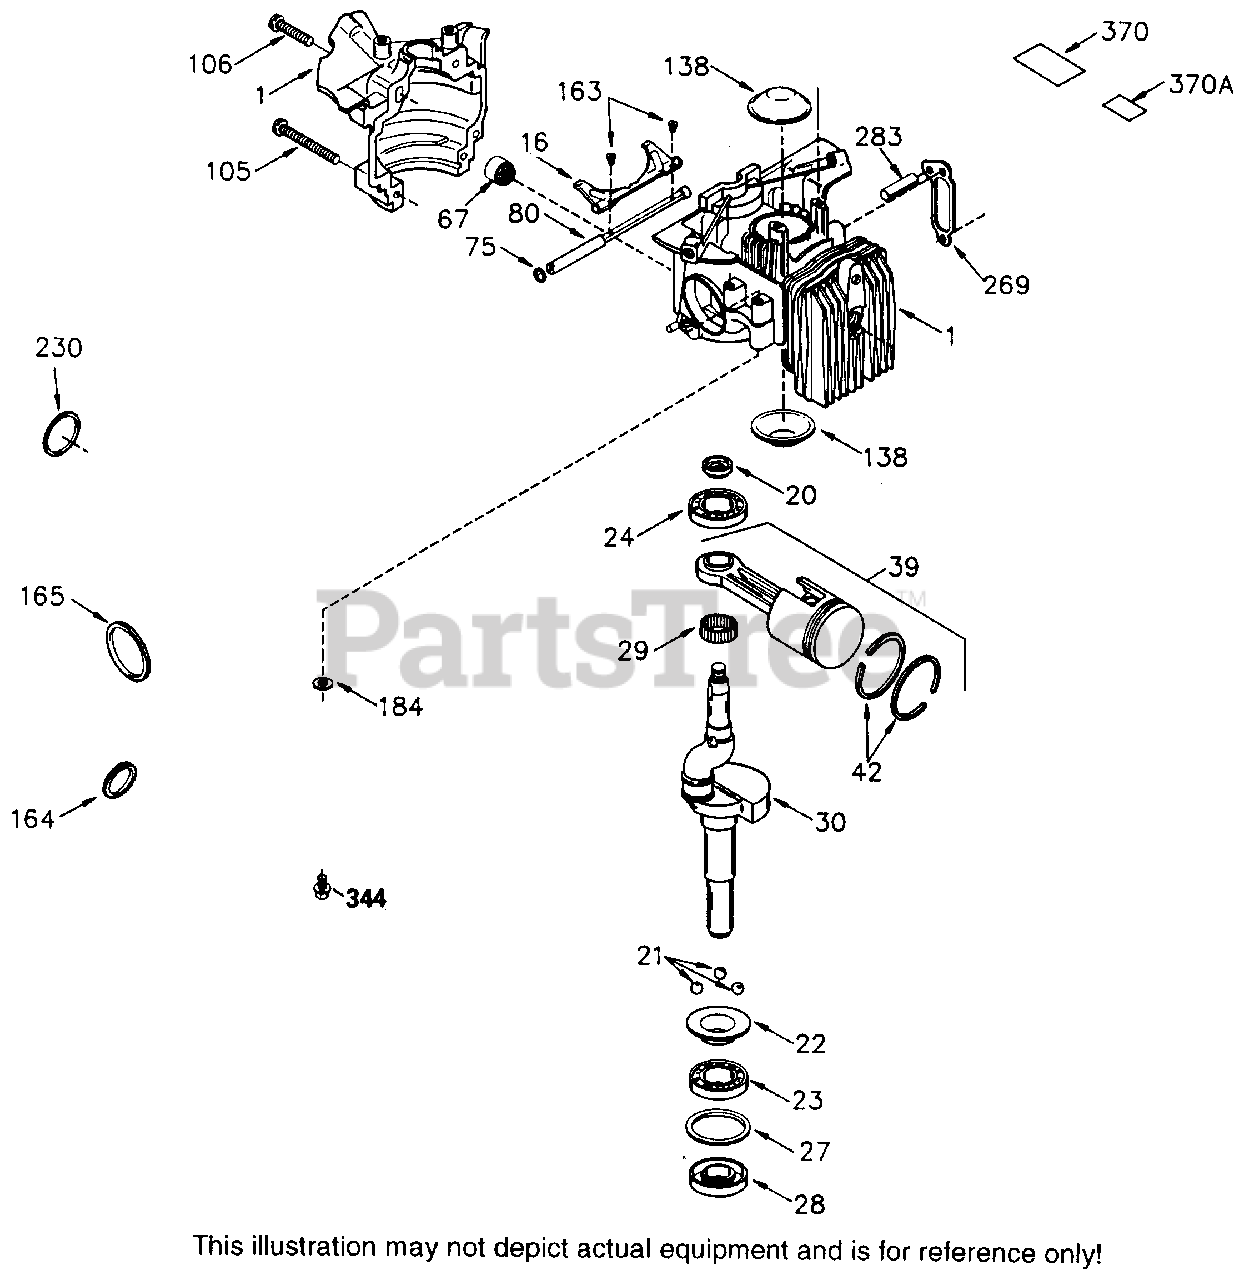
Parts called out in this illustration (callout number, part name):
1	"Cylinder (Incl. 67, 105, 106 & 138)
16	Lever, Governor
20	Seal, Oil (flywheel end)
22	Ring, Slide
23	Bearing, Ball
24	Bearing, Ball
27	Retainer, Bearing
28	Seal, Oil (PTO end)
29	Bearing Strip (31 needles)
30	Crankshaft
39	Piston & Rod Assy. (Incl. 29 & 42)
42	Ring Set, Piston
67	Filter, Fuel (w/brass collar)
75	Seal, Oil
80	Shaft, Governor
105	Screw, 5/16-18 x 1-5/8"
106	Screw, 5/16-18 x 2-3/16"
138	Cover, Port
163	Screw, 4-40 x 1/4"
164	"O" Ring
165	"O" Ring
230	"O" Ring
269	Gasket, Muffler
283	Pin, Spirol
344	Screw, 5/16-18 x 5/8"
370	Decal, Fuel mix
370A	Decal, Model & Serial No.
